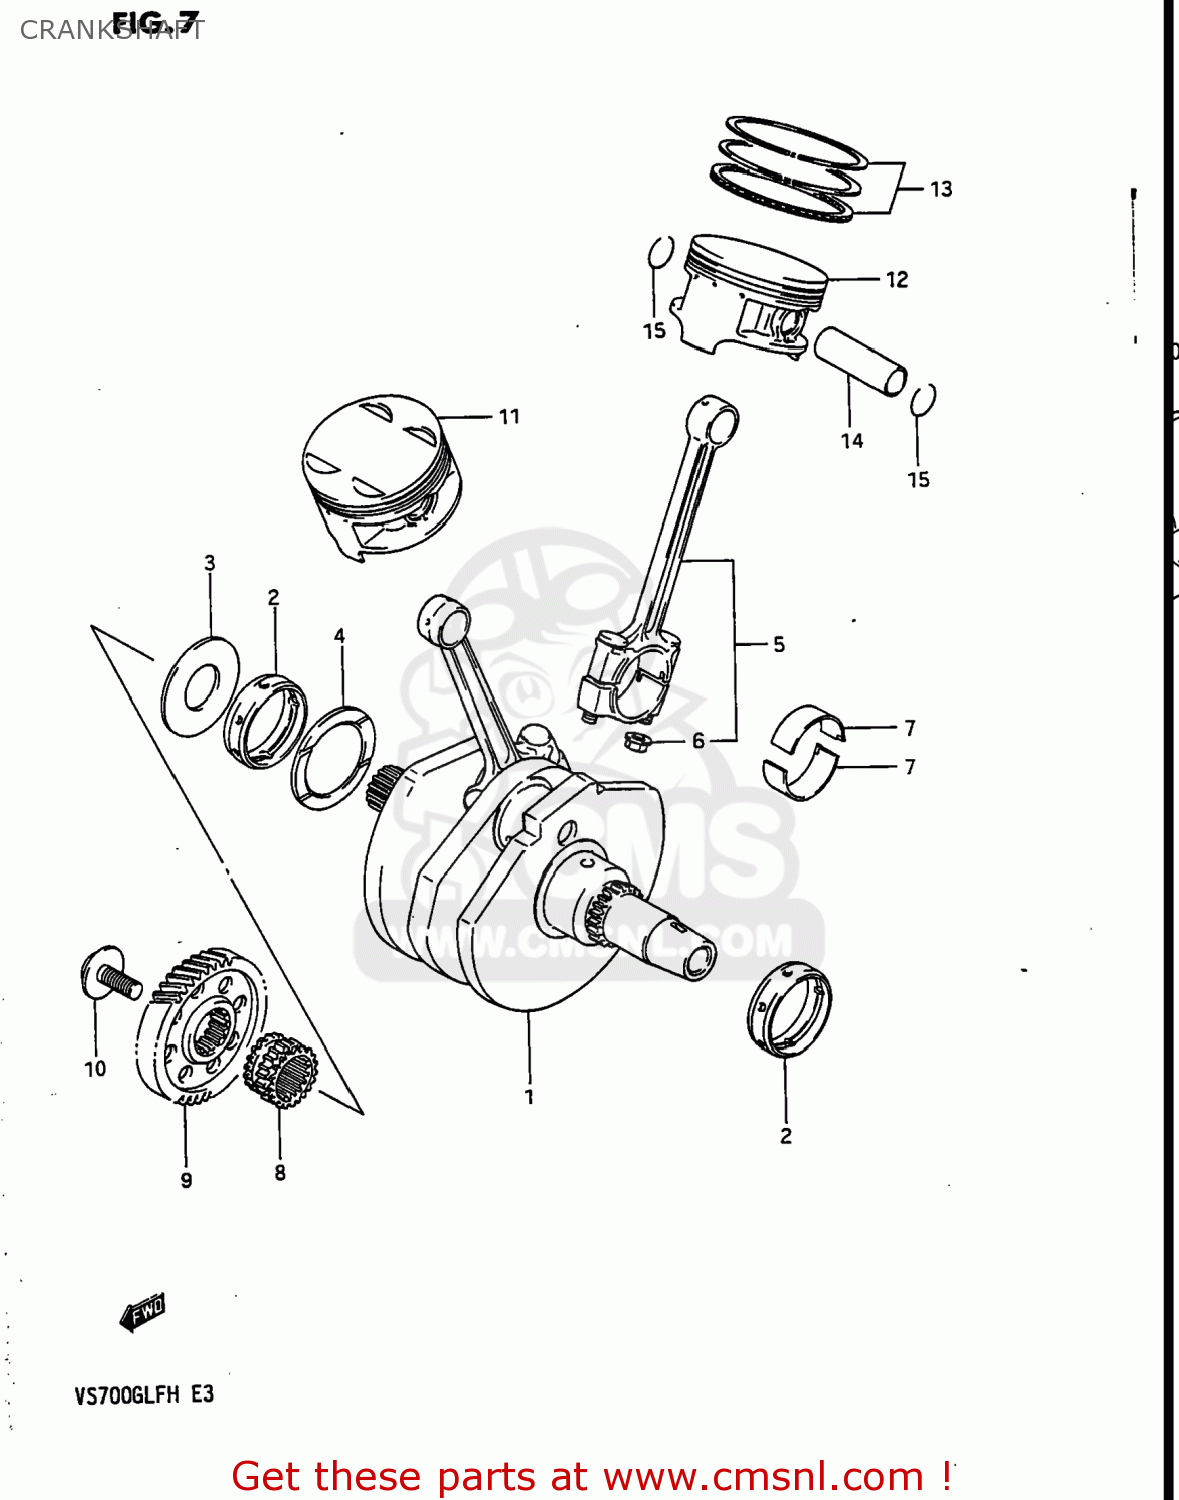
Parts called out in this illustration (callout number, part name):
1	CRANKSHAFT
2	METAL,CRANKSHAFT
3	WASHER,CRANK THRUST
4	WASHER(48.1X64X1.94)
5	CONNECTING ROD ASSY
6	NUT
7	BEARING,CRANK PIN
8	SPROCKET,CAM CHAIN DRIVE,R
9	GEAR,PRIMARY DRIVE
10	BOLT(12X28)
11	PISTON
12	PISTON
13	RING SET,PISTON
14	PIN,PISTON
15	CIRCLIP,PISTON PIN
